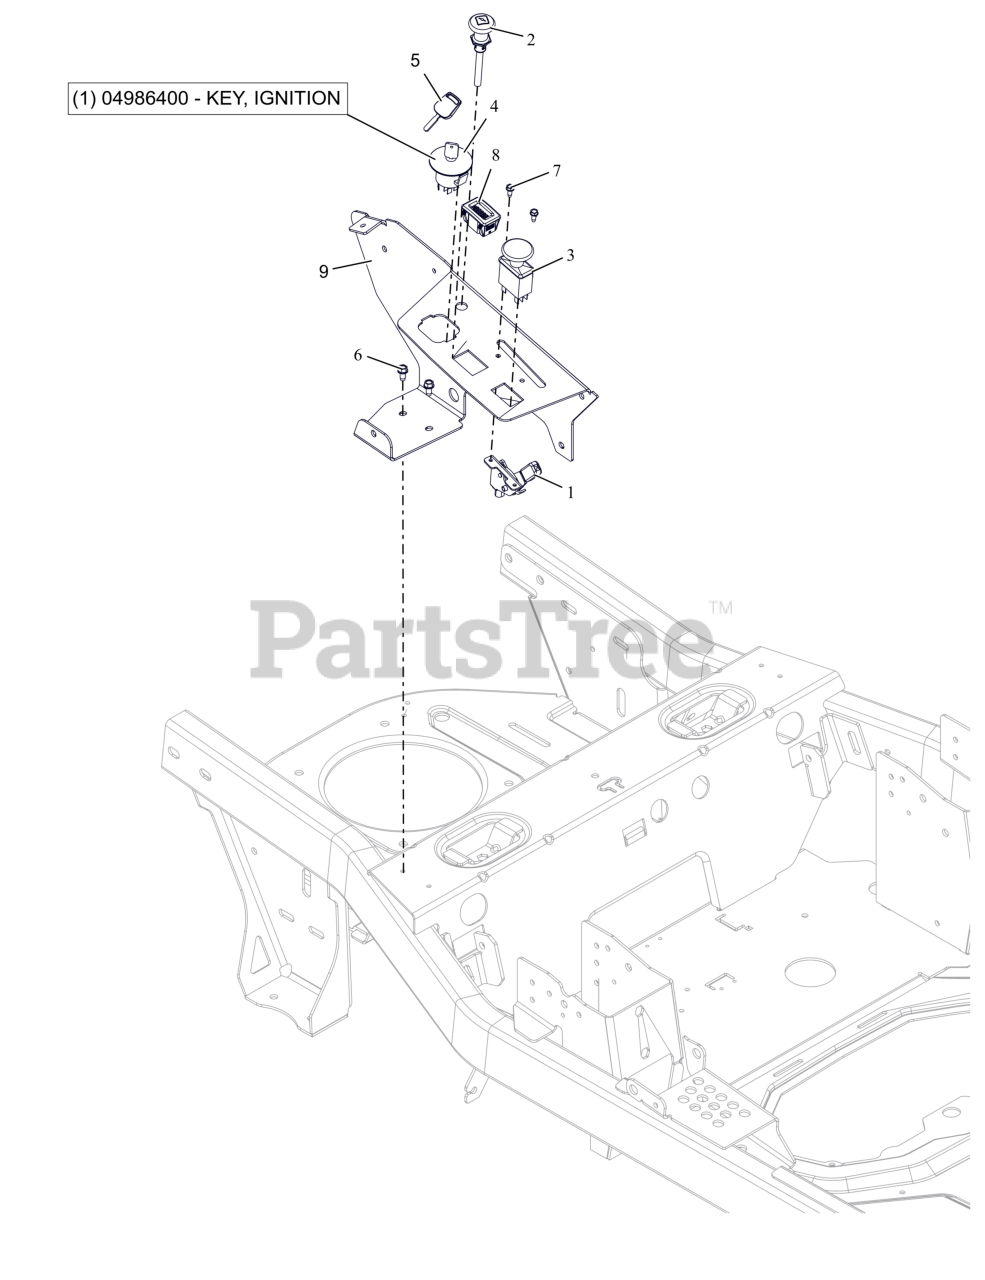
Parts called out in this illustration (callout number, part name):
1	CABLE- THROTTLE LH 90DEG 37"
2	CABLE- CHOKE-SNAP IN 37"
3	SWITCH, CLUTCH
4	KEYSWITCH-IGNITION 4 POS
5	KEY, IGNITION
6	SCR-TAP .25-20X.50 HWH ZCC
7	SCR,TAP #10-24X.50 HWH TR ZCC
8	METER, HOUR - NO PRINT
9	PANEL- CONTROL-RH-ARIENS
